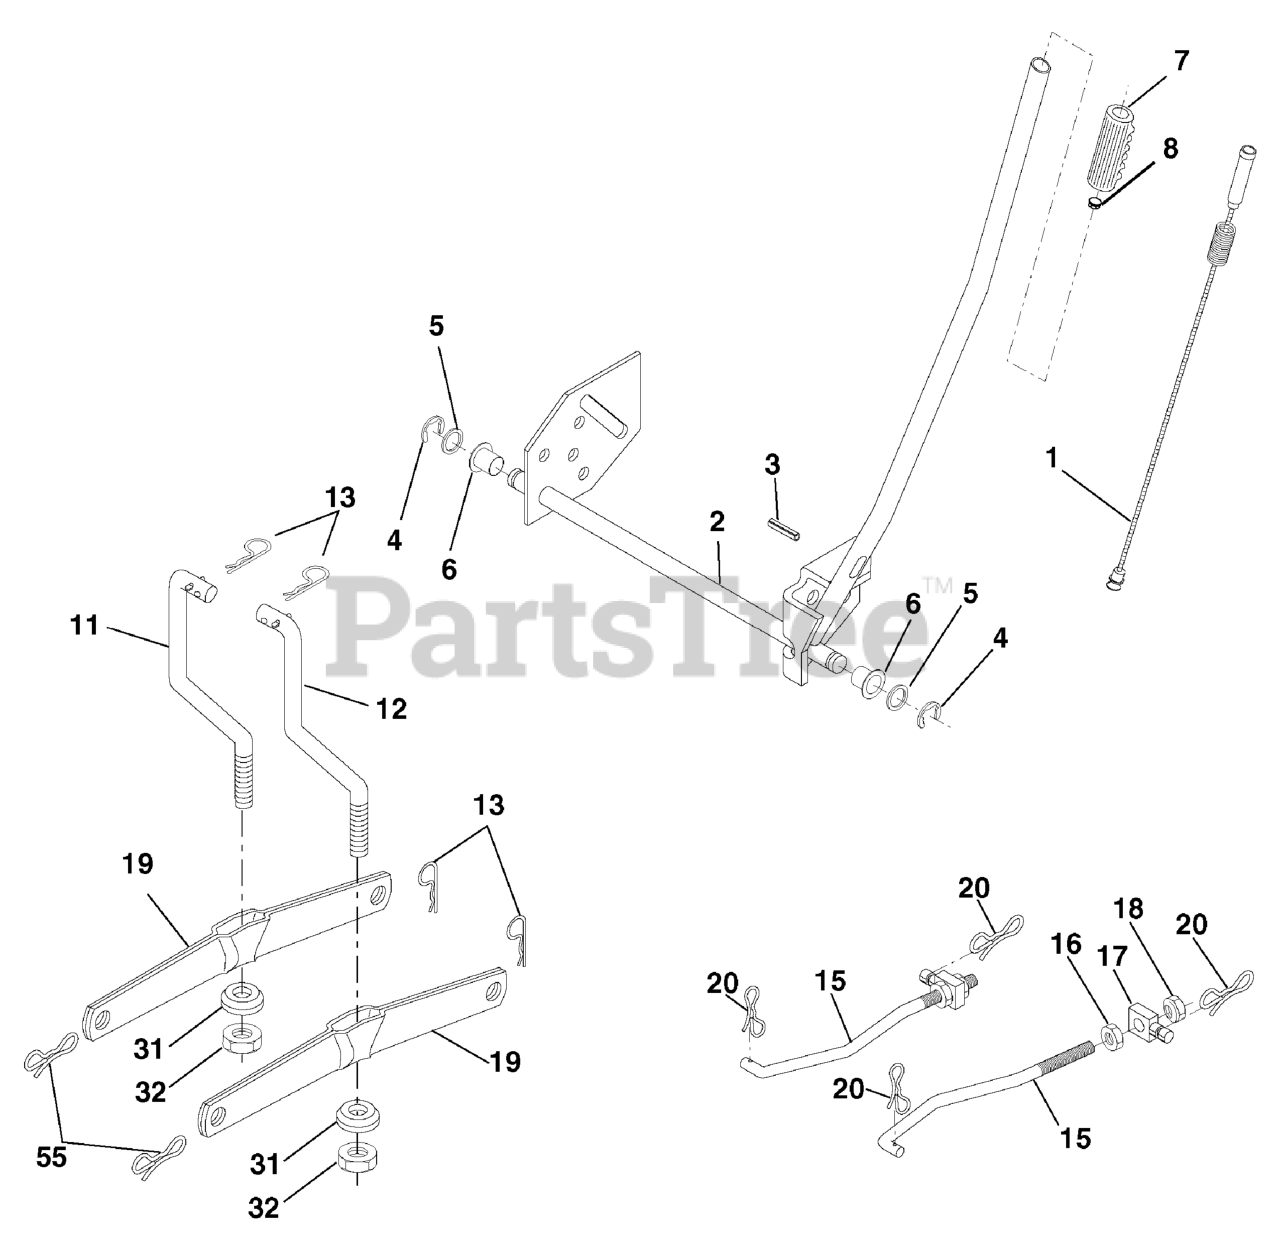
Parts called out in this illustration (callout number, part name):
1	PLUNGER, Assembly Lift LVR
2	SHAFT, Assembly, Lift
3	PIN, Groove
4	E-RING
5	WASHER, 21/32 x 1 x 21 Ga.
6	BEARING, Nylon
7	GRIP, Handle
8	BUTTON, Plunger, Red
11	LINK, Lift, LH
12	LINK, Lift, RH
13	RETAINER, Spring
15	LINK, Front
16	NUT, Hex, Jam 1/2-13 UNC
17	TRUNNION
18	LOCKNUT, Hex with Washer Insert, 1/2-13 UNC
19	ARM, Suspension Rear
20	PIN, Cotter Bow Tie Lock, 7/16
31	BEARING, Pvt Lift
32	NUT, Crownlock, 3/8-24
55	PIN, Cotter Bow Tie Lock, 5/16
